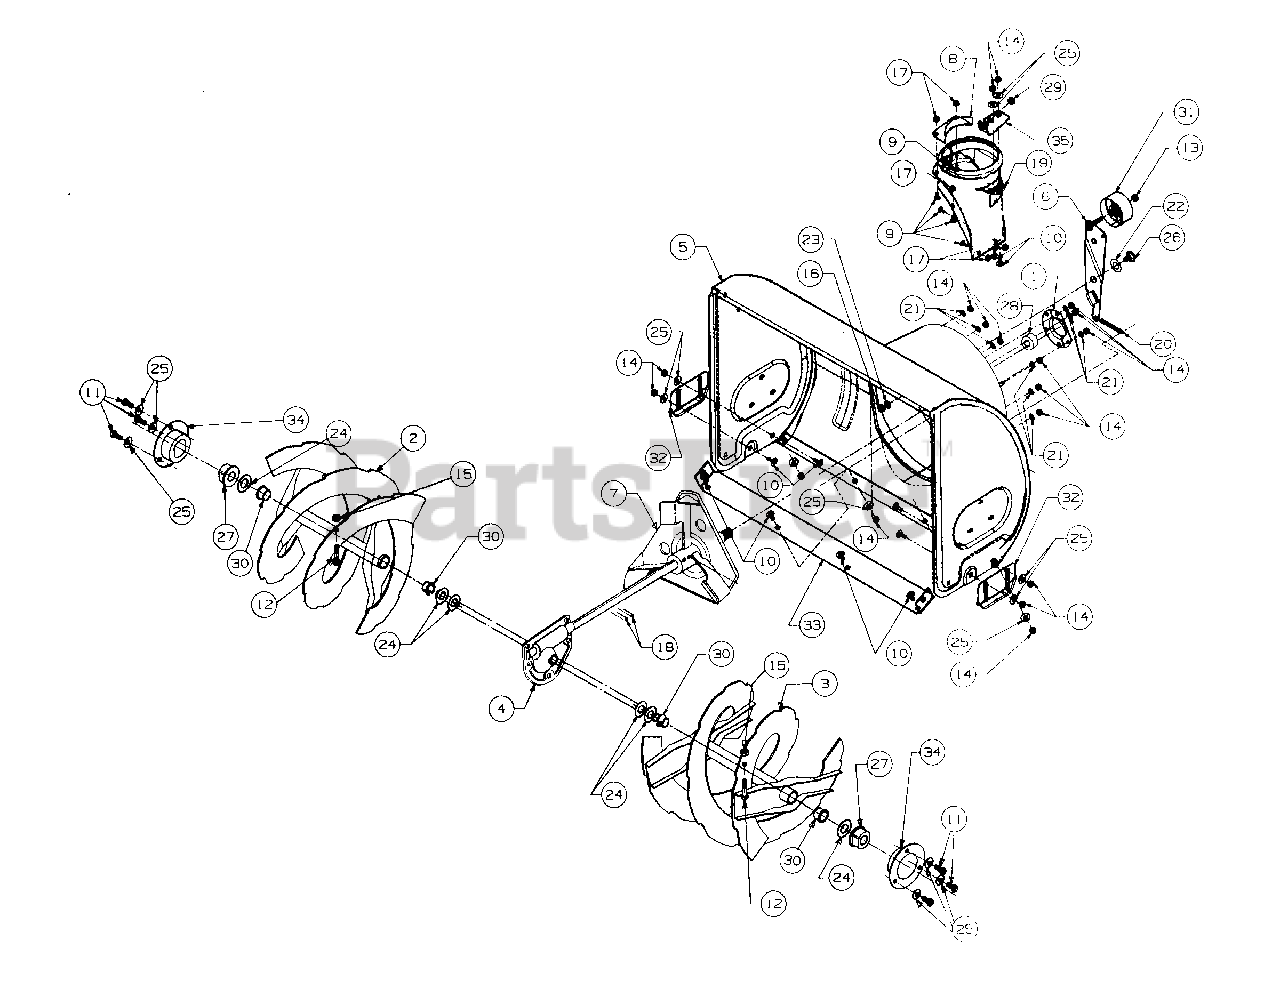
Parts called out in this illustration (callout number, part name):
1	Housing-Bearing
4	Gear Assembly 22"
9	Screw-Carriage
10	Screw-Carriage
11	Screw-Hex
12	Shear Bolt
13	Nut-Hex Lock
14	Nut-Hex
17	Nut-Hex Lock
18	Pin-Spring
19	Adapter-Chute
20	Spring
21	Washer-Lock
22	Washer-Flat
23	Washer-Lock
24	Washer-Flat
25	Washer-Bell
26	Screw-Shoulder
27	Bearing-Flange
28	Bearing Ball
29	Bushing-Plastic
30	Bushing-Flange
31	Idler-Flat
